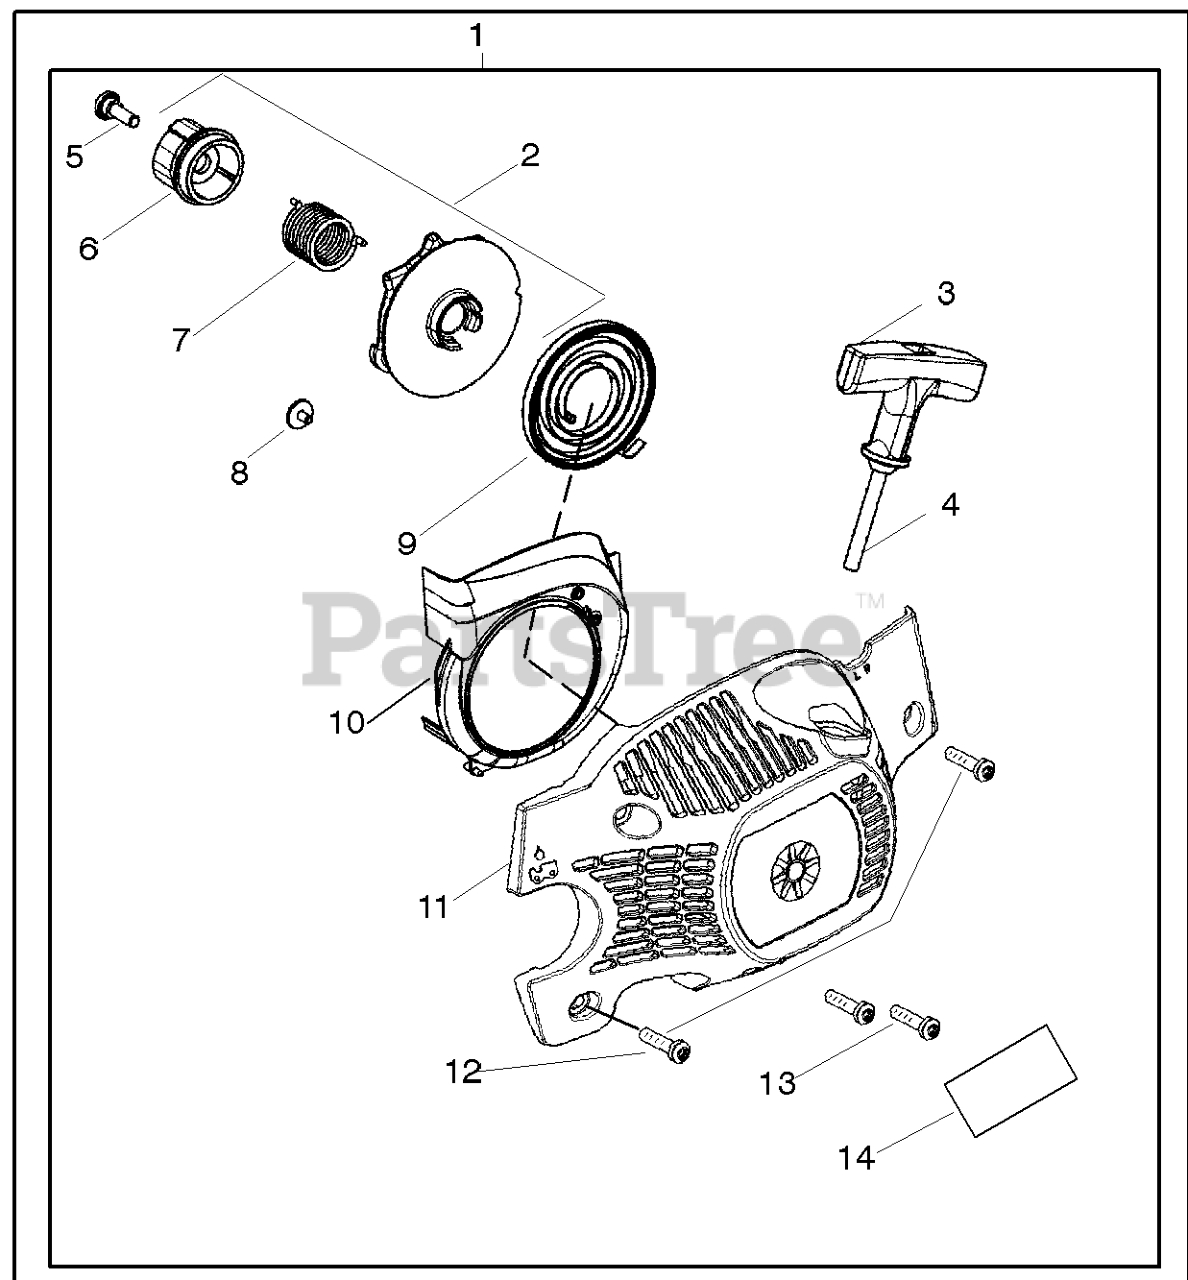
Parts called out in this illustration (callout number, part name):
1	KIT FAN HSG & STARTER EPS
2	KIT EPS STARTER
3	STARTER HANDLE GRAY
5	SCREW SHOULDER
6	HUB STARTER EPS
7	SPRING EPS
9	SPRING STARTER
10	BAFFLE AIR
11	HOUSING FAN W/ EYELET
13	SCREW,STRTR CVR 36/41
14	DECAL 137 STARTER
